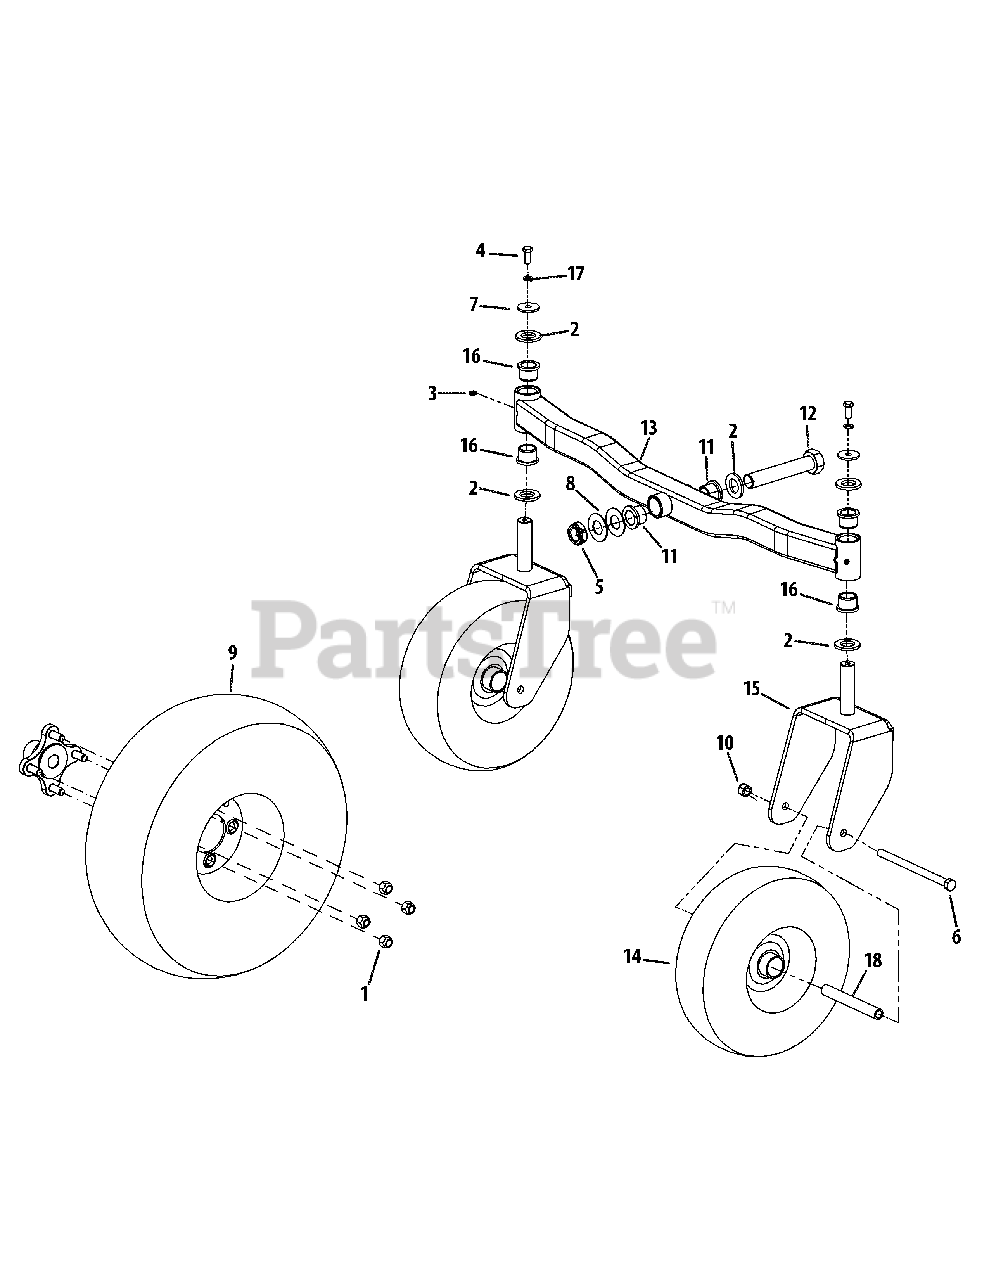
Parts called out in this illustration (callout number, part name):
1	Lug Nut, 1/2-20
2	Washer, 1.00 x 1.75 x .172
3	Grease Fitting, 1/4-28
4	Hex Screw, 3/8-16 x .880
5	Jam Nut, 1-14
6	Hex Screw, 1/2-20 x 7.50
7	Washer, .390 x 1.50 x .122
8	Washer, 1.00 x 2.00 x .075
9	Wheel Assy., 20 x 8-10 (44" Deck)
9	Wheel Assy., 20 x 8-10 (48" Deck)
9	Wheel Assy., 20 x 10.00 x 10 (54" Deck)
10	Nylock Nut, 1/2-20
11	Flange Bearing, 1.001 x 1.25
12	Hex Screw, 1-14 x 5.5
13	Front Axle Weldment
14	Wheel Assembly, 13 x 5-6
15	Castor Wheel Mount Bracket Assy.
16	Flange Bearing, 1.000 x 1.254
17	Lock Washer, 3/8
18	Spacer, .51 x .75 x 5.825
